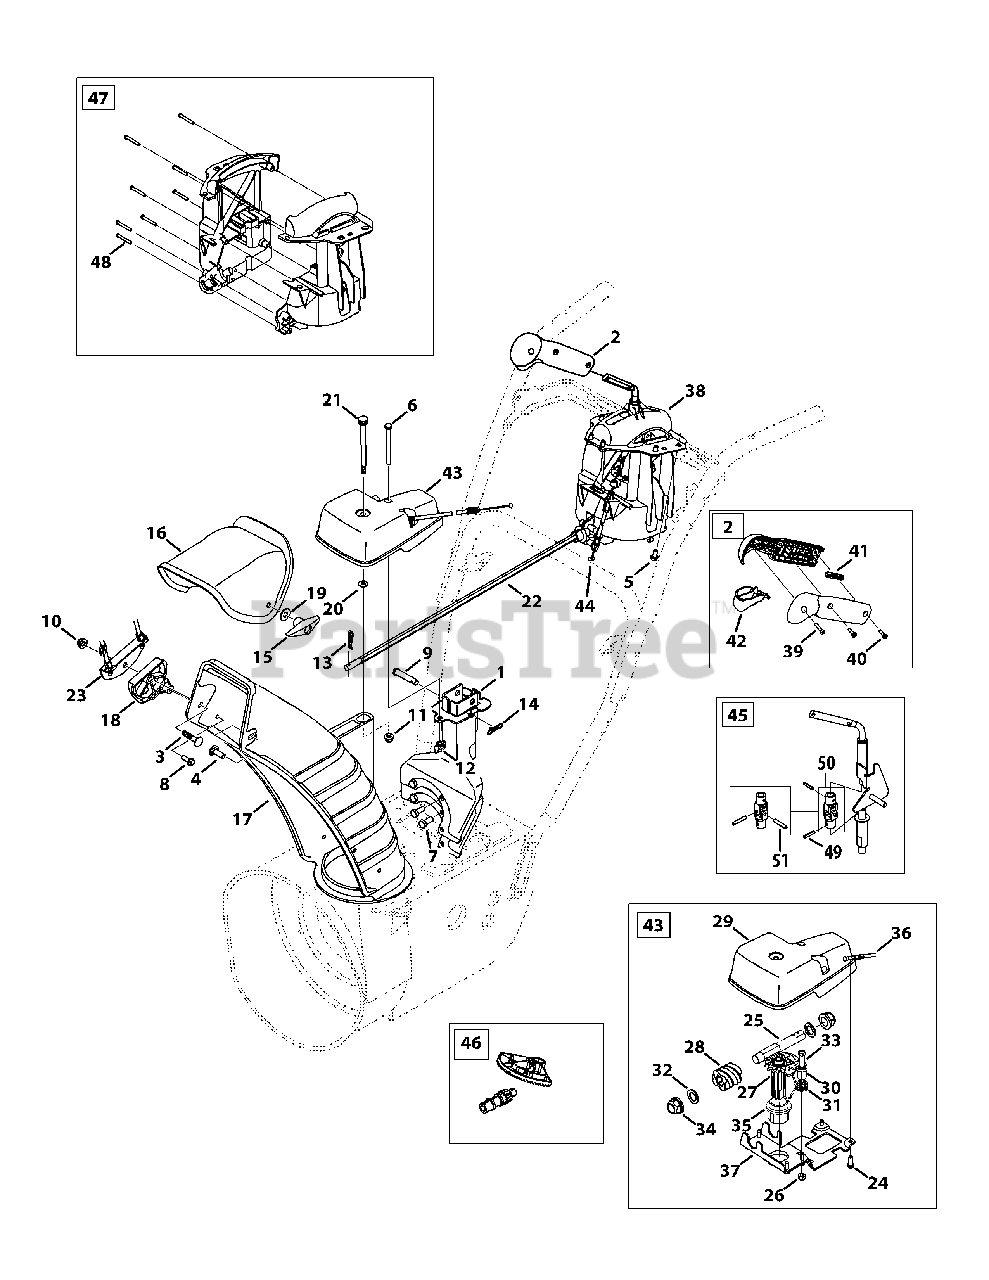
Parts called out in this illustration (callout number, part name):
1	Chute Support Bracket
2	Trigger Housing
3	Bolt, Carriage, 5/16-18 x 1.50, 4-Way
3	Bolt, Carriage, 5/16-18 x .750, 2-Way
4	Bolt, Carrier, 5/16-18 x 1.00
5	Screw, Hi-Lo, 1/4-15 x 0.50
6	Hex Head Screw, 1/4-20 x 3.00
7	Hex Head Screw, 5/16-24 x .750
8	Screw, Hi-Lo, 1/4-15 x 0.750
9	Clevis Pin, 3/8 x 1.87
10	Nut, Flange Lock, 5/16-18
11	Nut, Flange Lock, 1/4-20
12	Wing Nut, 1/4-20
13	Internal Cotter Pin
14	Bow-Tie Cotter Pin
15	Wing Knob, 5/16-18
16	Chute, Upper, 4-Way
16	Chute, Upper, 2-Way
17	Chute, Lower
18	Cable Guide, Chute Tilt
19	Washer, Flat, .349 x .879
20	Washer, Flat, .25 x .630
21	Screw, Shoulder, .312 x 3.5 x 1/4-20
22	Chute Rod, 3/8 Hex
23	Cable Bracket
24	Screw, 12-16 x .75
25	Hex Shaft
26	Hexlock Nut, 1/4-28
27	Gear, 14 T
28	Worm
29	Gear Cover
30	Pawl Lock
31	Torsion Spring, .721 ID x .474
32	Washer, Flat, .625 x 1.0 x .067
33	Screw, Shoulder, .34 x .95 x 1/4-28
34	Hex Bearing
35	Flange Bearing
36	Cable Lock
37	Gear Bracket
38	Chute Control, 4-Way
38	Chute Control, 2-Way
38	Chute Control Housing, 4-Way
38	Chute Control Housing, 2-Way
38	Gear Set
39	Screw, #8 x 1.00
40	Screw, 8-32 x .750
41	Joystick Plug
42	Joystick Trigger
43	Chute Rotation Gearbox
44	4-Way Cable
44	4-Way Cable w/Clip
45	Shift Assembly
46	Gear Set Assembly
47	Handle Housing Assembly
48	Screw, #8-18 x 1.250
49	Pin, Roll
50	Block, Asm Joint
51	Pin, Roll 3/16 x 1.1
